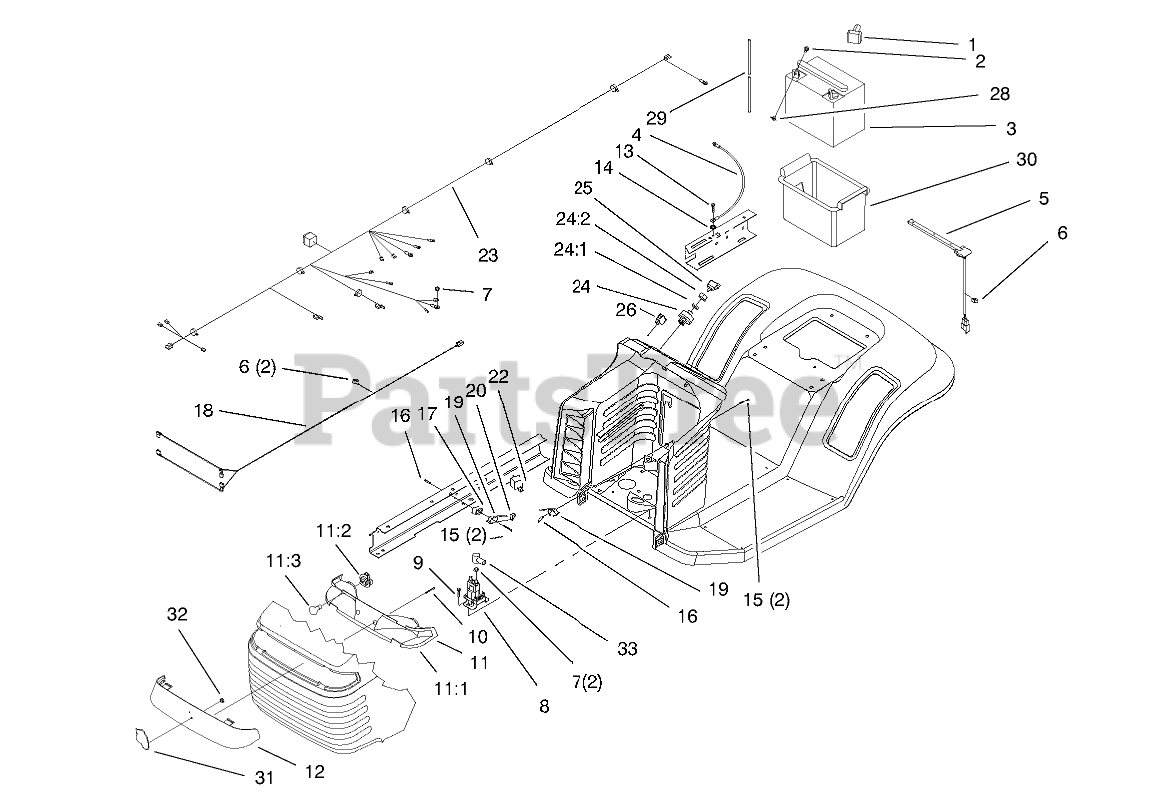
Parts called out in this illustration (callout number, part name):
1	BOOT-TERMINAL
2	SCREW-HH
3	Battery
4	WIRE ASM
5	SWITCH-SEAT
6	CLIP-RETAINER, WIRE
7	NUT-KEPS
8	Solenoid
9	SCREW-HWH
11	HEADLIGHT REFLECTOR ASM
11:1	REFLECTOR-LIGHT
11:2	SOCKET-LIGHT
11:3	BULB
12	LENS-HEADLIGHT
13	SCREW-HWH
14	WASHER-LOCK/EXT
15	SCREW-HH
16	NUT-SPEED
17	SPACER
18	HARNESS-WIRE, LIGHTS
19	SWITCH-MICRO
20	PLUNGER-SEAL
22	RELAY
23	WIRE HARNESS
24	Key Switch ASM
24:1	WASHER-TOOTH, INTERNAL
24:2	NUT-HH
25	KEY-IGNITION
26	SWITCH-ROCKER
28	NUT-WING
29	TUBE-BATT DRAIN/80-2600
30	BOX-BATTERY
31	EMBLEM-GRILLE WHEELHORSE
33	BOOT-TERMINAL INSULATOR
